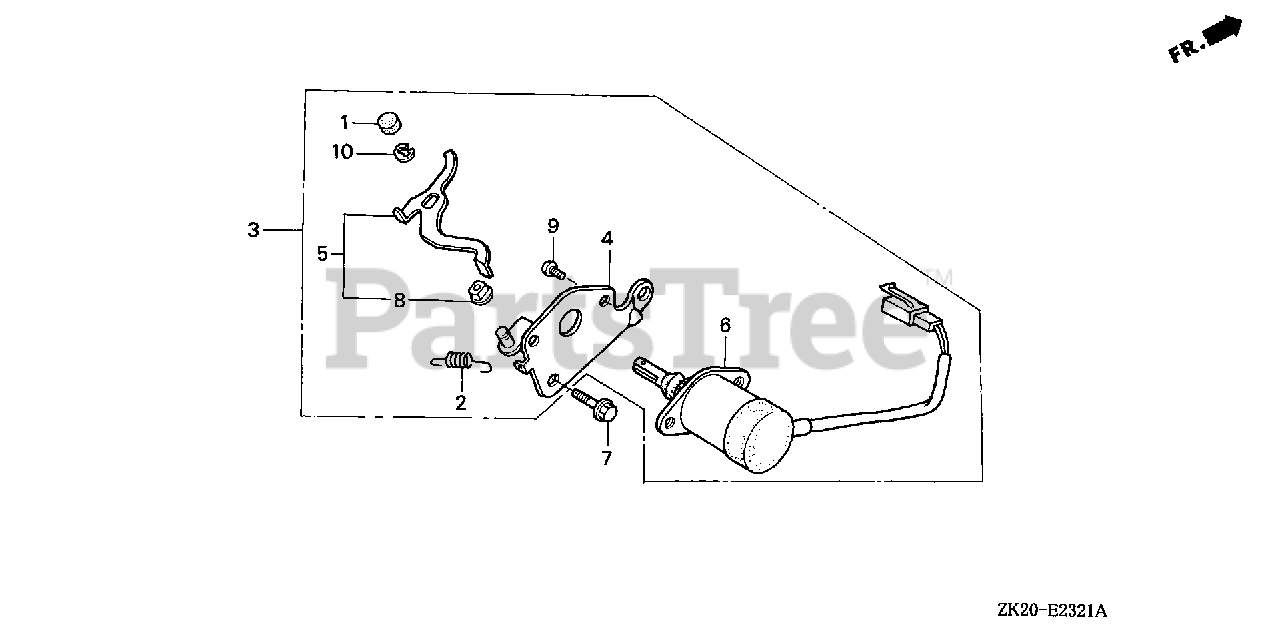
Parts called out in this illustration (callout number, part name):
1	CAP, CHOKE LEVER
2	SPRING, CHOKE RETURN
3	AUTO-THROTTLE ASSY.
4	STAY, SOLENOID THROTTLE
5	LEVER, SOLENOID THROTTLE
6	SOLENOID ASSY.
7	BOLT, FLANGE (6X12) (CT200)
8	BUSH, AUTO-THROTTLE LEVER
9	SCREW, PAN (5X8)
10	E-RING (4MM)
